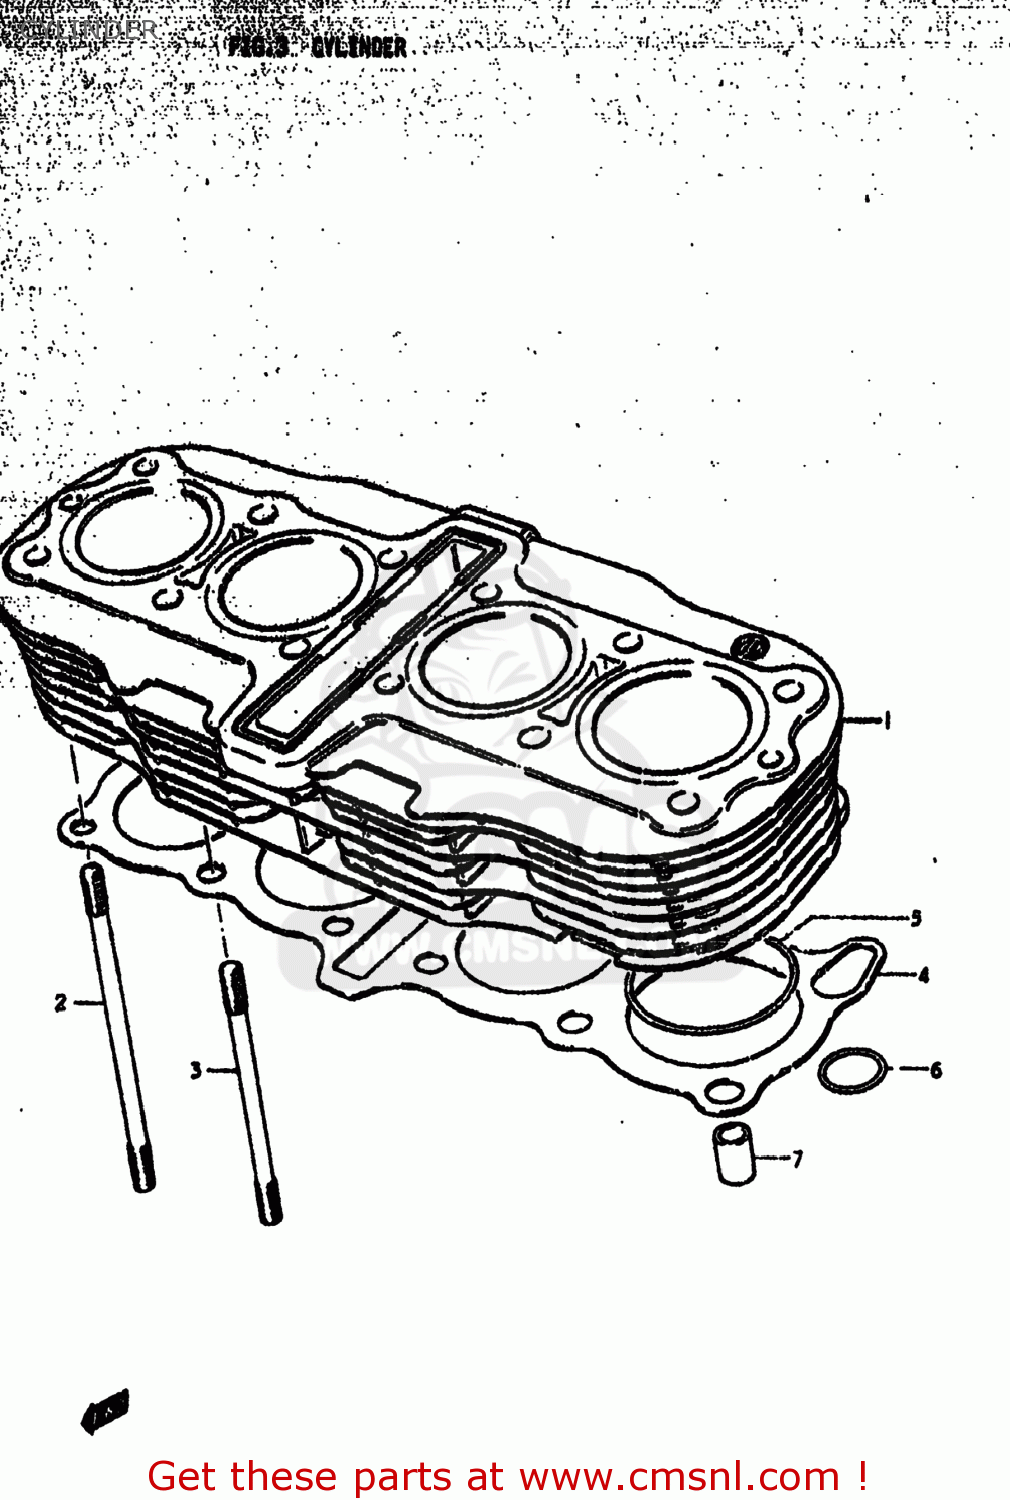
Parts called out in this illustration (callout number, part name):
1	CYLINDER
2	STUD
3	STUD
4	GASKET,CYLINDER (MCA)
5	O RING(D:2,ID:70)
6	O RING(D:3.05)
7	PIN
